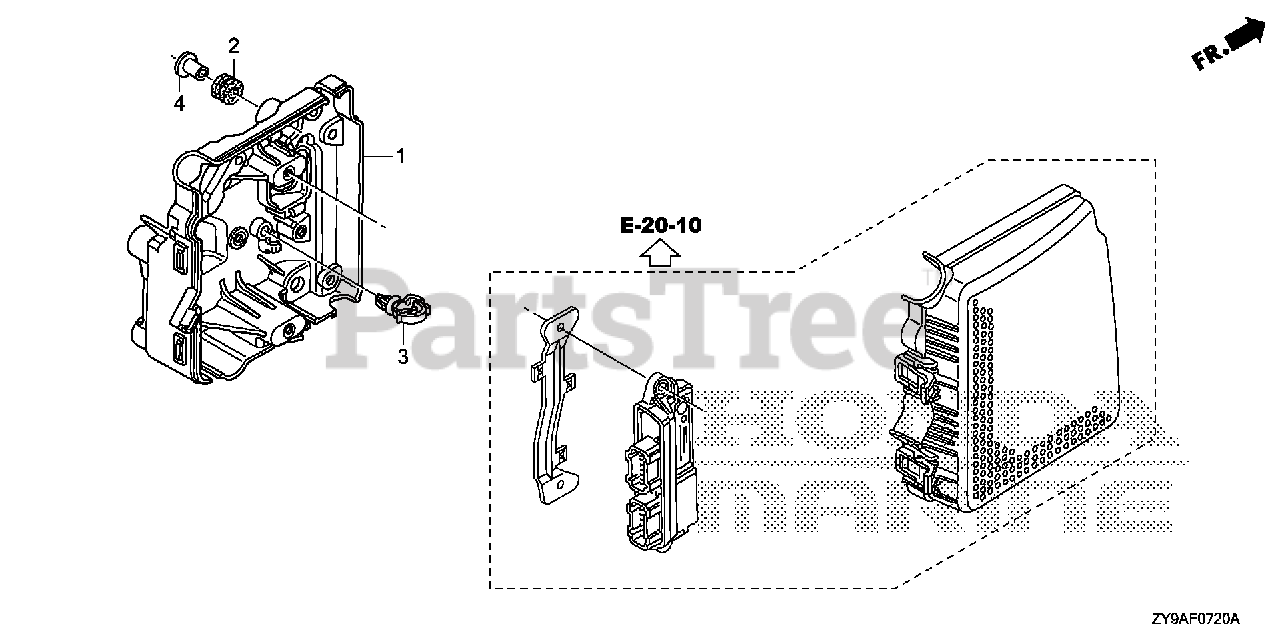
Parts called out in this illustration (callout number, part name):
1	CASE, ELECTRONIC PARTS
2	GROMMET, ELECTRONIC PARTS CASE
3	CLIP, WIRE HARNESS
4	COLLAR, MODULE IGNITION CONTROL CASE (CDI)
